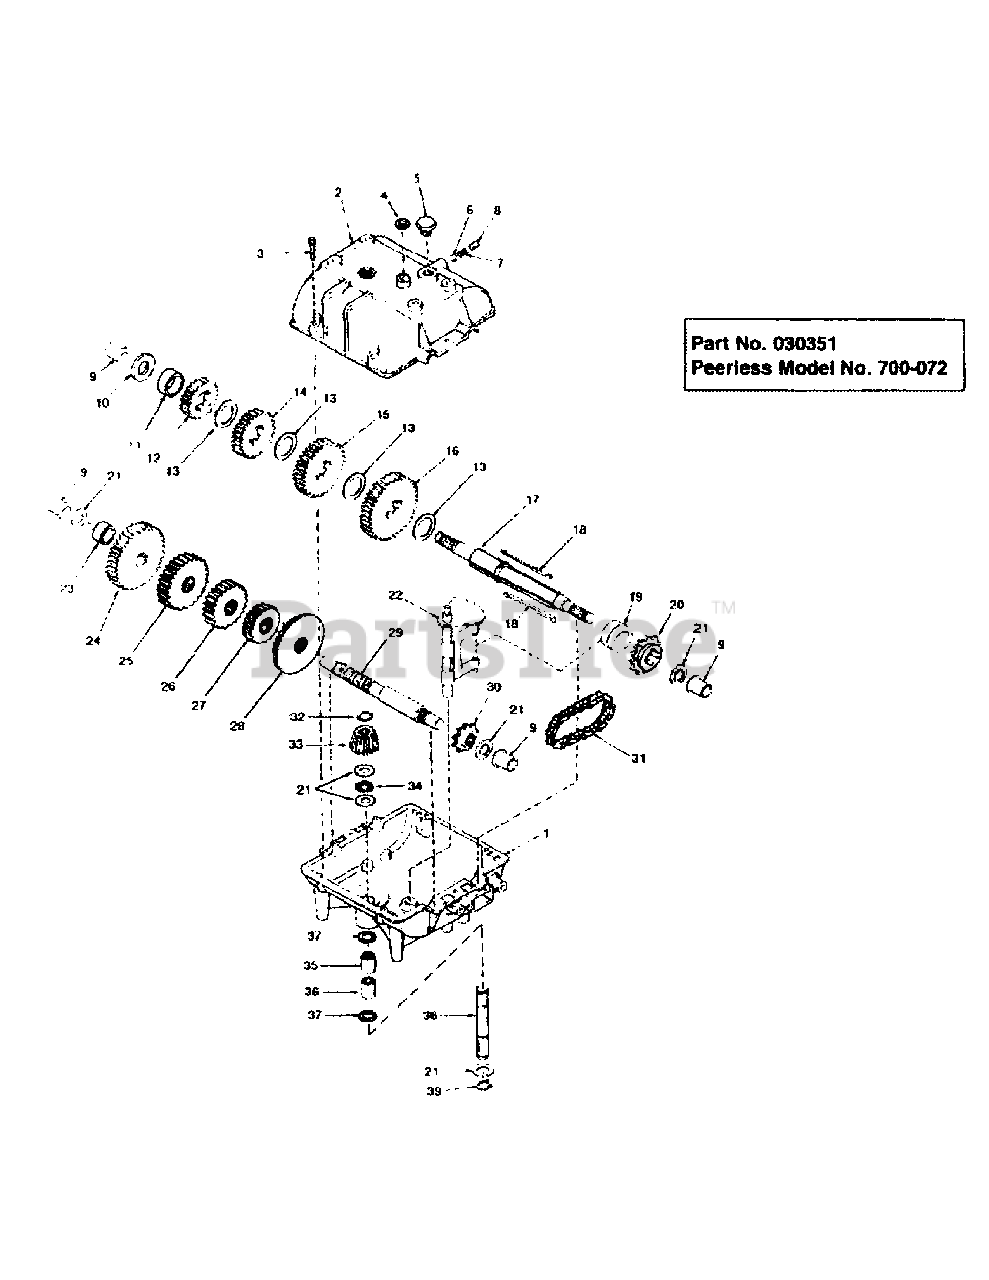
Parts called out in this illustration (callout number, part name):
1	Transmission case
2	Transmission cover
3	Cap screw
4	Seal, square cut
5	Threaded plug
6	Steel ball, 5/16" dia
7	Spring
8	Set screw
9	Flange bushing
10	Thrust washer
11	Spacer
12	Spur gear (30 teeth)
13	Thrust washer
14	Spur gear (32 teeth)
15	Spur gear (35 teeth)
16	Spur gear (37 teeth)
17	Shaft-output/brake
18	Key, shift
19	Shift collar
20	Sprocket (18 teeth)
21	Thrust washer
22	Rod & fork, shift
23	Spacer
24	Spur gear (20 teeth)
25	Spur gear (18 teeth)
26	Spur gear (15 teeth)
27	Spur gear (12 teeth)
28	Spur gear (42 teeth)
29	Counter shaft
30	Sprocket (9 teeth)
31	Roller chain (#41, 24 links)
32	Retaining ring
33	Bevel pinion, input
34	Thrust bearing
35	Needle bearing
36	Needle bearing
37	O-ring
38	Input shaft
39	Retaining ring
